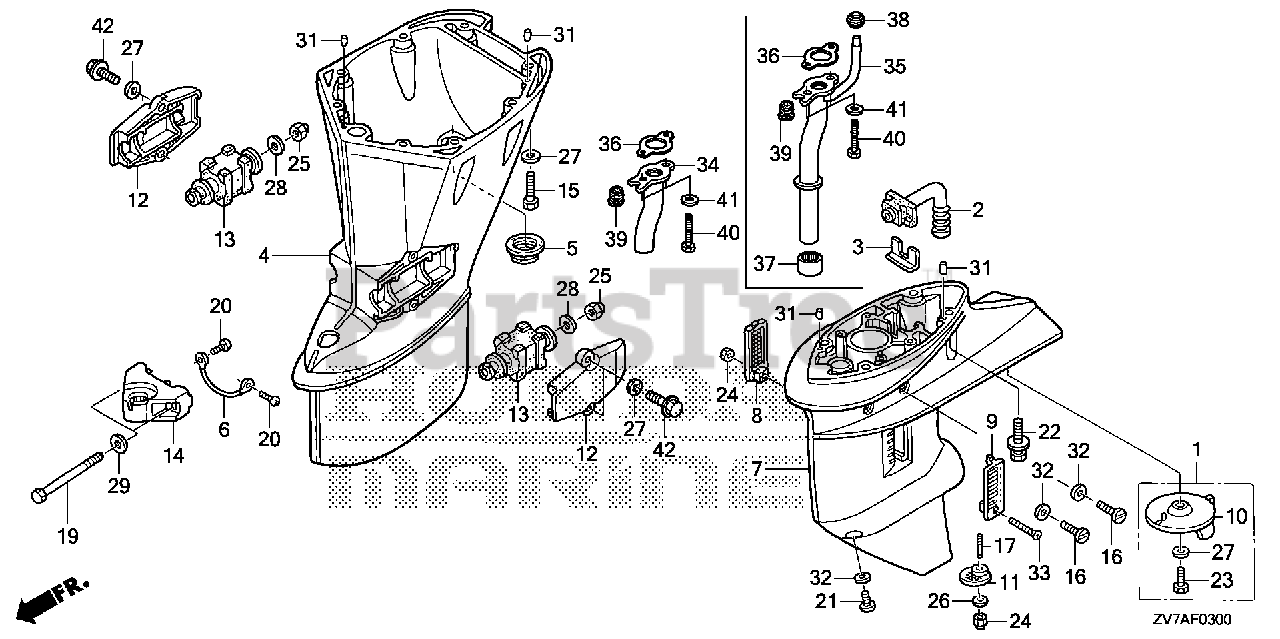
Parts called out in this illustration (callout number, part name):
1	TAB KIT, TRIM
2	TUBE, WATER (LOWER)
3	PLATE, RUBBER SETTING
4	CASE, EXTENSION *NHB14M* (L) (AQUA MARINE SILVER METALLIC)
5	RUBBER, DRAIN PLUG
6	WIRE, LEAD (1.5X116MM)
7	CASE, GEAR *NH282MU* (OYSTER SILVER METALLIC-U)
7	CASE, GEAR *NHB14M* (AQUA MARINE SILVER METALLIC)
8	SCREEN, R WATER
9	SCREEN, L. WATER
11	SCREEN, WATER (LOWER)
12	HOUSING, R. MOUNTING (LOWER) *NHB14M* (AQUA MARINE SILVER METALLIC)
13	RUBBER, MOUNT (LOWER)
14	HOUSING, CENTER MOUNTING (LOWER) *NHB14M* (AQUA MARINE SILVER METALLIC)
15	BOLT, HEX. (8X35)
16	BOLT, OIL CHECK
17	BOLT, STUD (5X12)
19	BOLT, HEX. (12X162)
20	SCREW, PAN (6X8)
21	BOLT, DRAIN PLUG
22	BOLT-WASHER (10X40)
23	BOLT, HEX. (8X20)
24	NUT, SELF-LOCK (5MM)
25	NUT, SELF-LOCK (12MM)
26	WASHER, PLAIN (5MM)
27	WASHER, PLAIN (8MM)
28	WASHER, PLAIN (12MM)
29	WASHER, PLAIN (12MM)
31	PIN, DOWEL (6X10)
32	O-RING (6.9X1.45)
33	SCREW, OVAL (5X28)
36	GASKET, EX. PIPE
37	GROMMET, EX. PIPE
38	GROMMET, EX. BREATHER PIPE
39	GROMMET, WATER TUBE
40	BOLT, HEX. (8X25)
41	WASHER, PLAIN (8MM)
42	BOLT, FLANGE (8X25)
